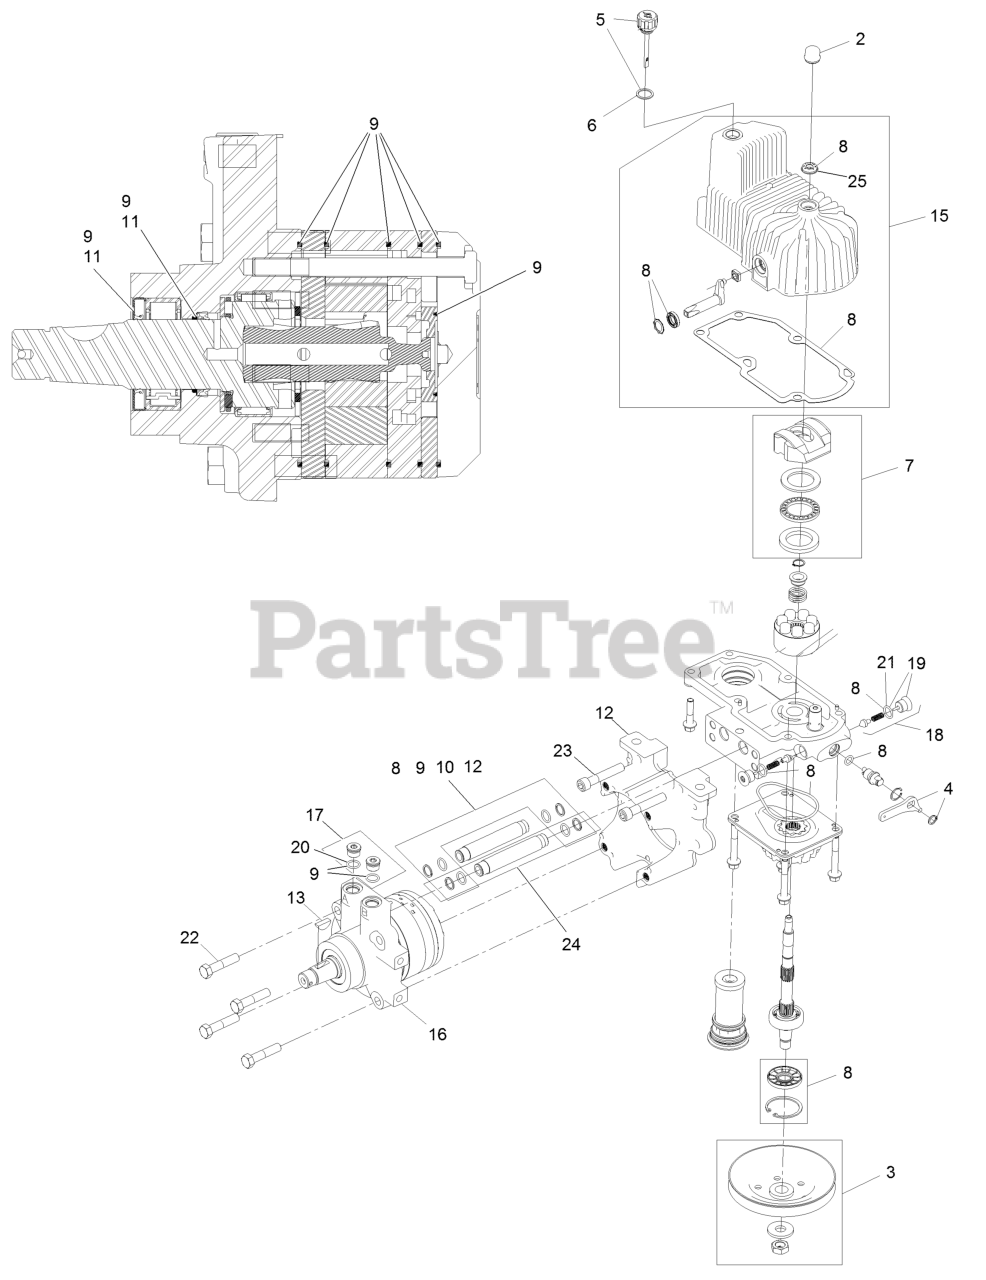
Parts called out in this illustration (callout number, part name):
2	COVER-SHAFT, HYDRO
3	PULLEY KIT
4	HANDLE-BYPASS VALVE, HYDRO
5	DIPSTICK-HYDRO W/GASKET
6	GASKET-DIPSTICK, HYDRO
7	SWASH BLOCK KIT
8	PUMP SEAL KIT
9	MOTOR SEAL KIT
10	TUBE SEAL KIT
11	OUTPUT SHAFT SEAL KIT
12	NOSE CUP-UHT
13	KEY-WOODRUFF
15	HOUSING-HYDRO, LH
16	MOTOR-HYDRAULIC LH 240CC
17	MAGNETIC PLUGS SERVICE KIT
18	CHECK VALVE ASM
19	PLUG-CHECK (W/O-RING)
21	O-RING-CHECK VALVE
22	SCREW HH
23	SCREW-HSH
24	HYDRAULIC TUBE KIT
25	SEAL-FAN DRIVE
